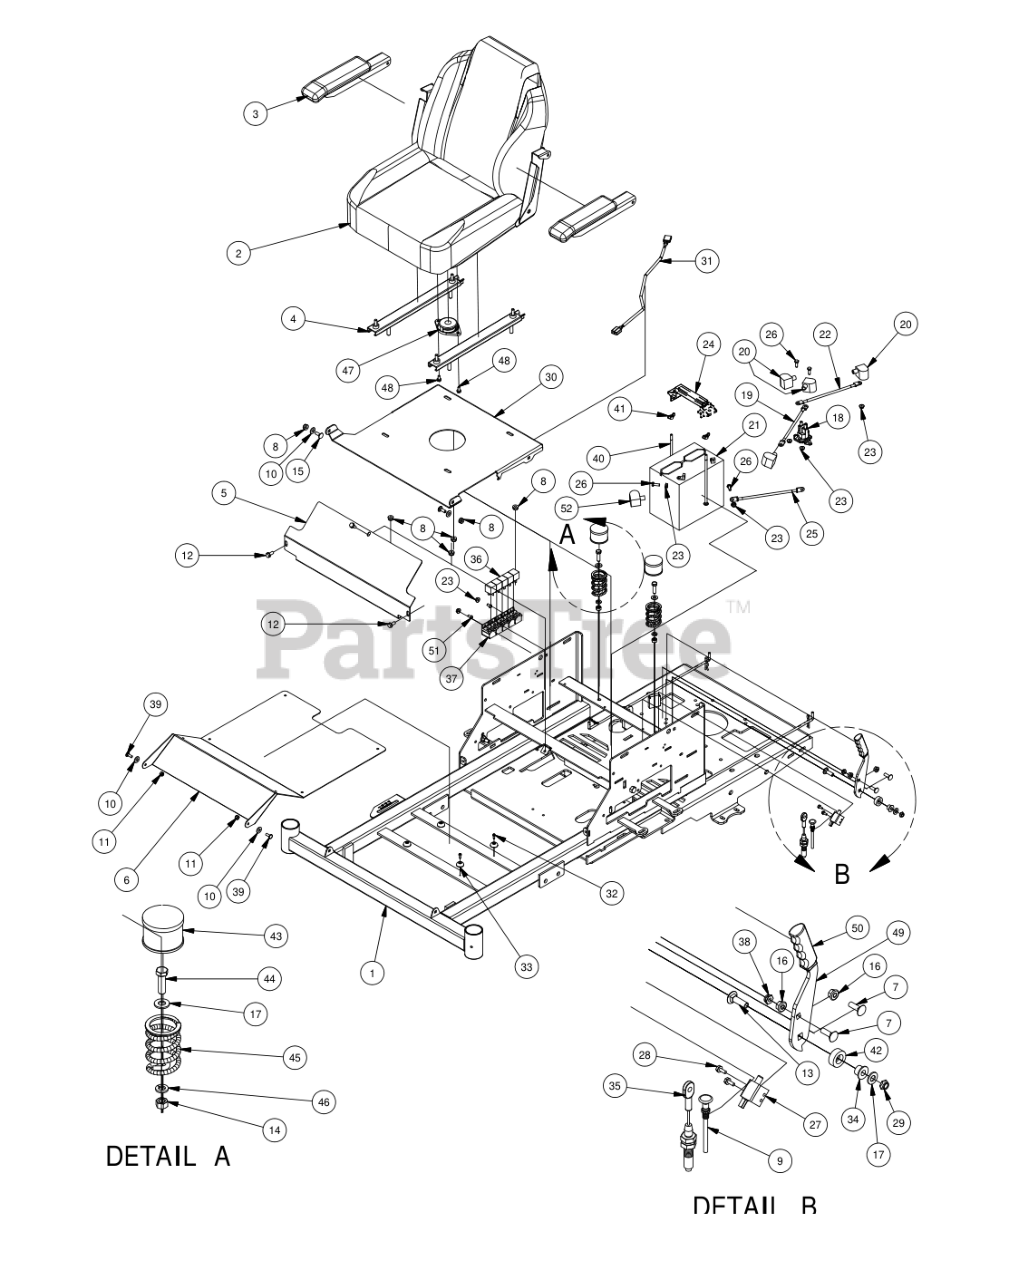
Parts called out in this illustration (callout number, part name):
2	2013 ZT Seat
4	Seat Rails
5	Zt Front Cover
6	ZT Floor Panel
7	5/16" x 1" Carriage Bolt
8	5/16-18 Nylon Flange Nut
10	.360 ID Plastic Washer
11	1/4" Nylock Nut
12	5/16 x 3/4 washer head type F screw
13	3/8" x 1 1/4" Carriage Bolt
14	3/8" Hex Nut
15	5/16" x 7/8" Carriage Bolt
16	5/16" Flange Nut
17	3/8" Flat Washer
19	24" Red Battery Cable
22	12 in red battery cable
23	1/4-20 Hex Flange Nuts Zinc w/Serrations
24	Battery Hold Down
25	Ground Cable
26	1/4-20 x 3/4 GR 5 Hex Bolts Zinc
27	Safety Switch
28	12-24x 1/2 HWH Bolt
29	3/8-16 Centerlock Half Nut
30	Seat Plate 2016
31	Seat Switch Adapter
32	#10 x 1/2" Self Tapping Screw
33	Button Bumper
34	Bronze Bushing SF-1220-8
35	Brake Cable
37	Wire Harness
38	5/16-18 Nylock Jam Nut 1/2 Nut
39	1/4" x 3/4" Carriage Bolt
40	1/4-20 X 8 Carriage Bolt
41	1/4" Wing Nut
42	2015 Brake Lever Spacer
43	Spring Cap Cover
44	3/8" x 1 1/4" Hex Bolt
45	Seat Spring
46	3/8" Lock Washer
47	Seat Safety Switch
48	1/4-20x1/2 HWH Bolt Slot
49	Brake Handle Cam Over
50	Rubber Brake Grip-cZT/ZT 2013
51	1/4" x 1/2" BS C/S 18-8 SS
52	Black Boot For Ground Cable
